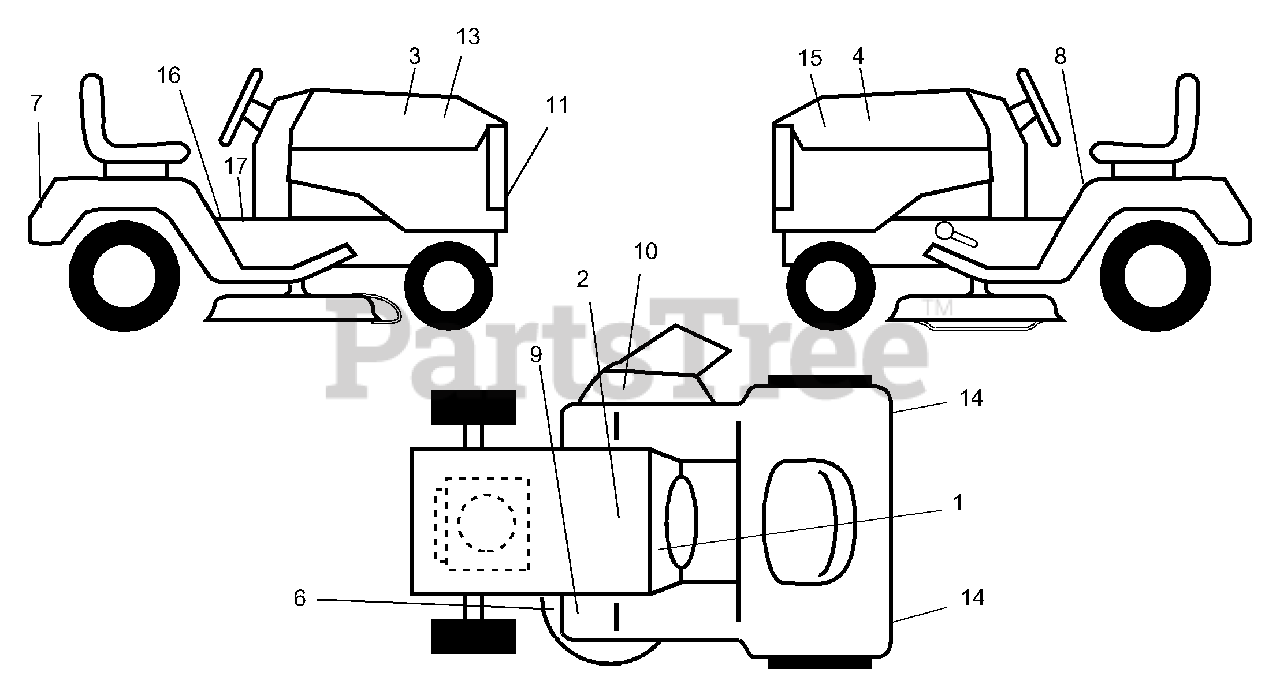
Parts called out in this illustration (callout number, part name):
1	Decal Instruction Dash Eng/fr
2	Decal Bat DAN/POI P/L Symbols
3	Decal Hood RH Husq
4	Decal Hood LH Husq
6	Decal V-Belt Sch
7	Decal Fender Husqvarna
8	Decal Caution Fender Eng/fr
9	Decal Clutch/brake Eng/fr
10	Decal Warning MULT-LANGUAGE
11	Decal Grille Husqvarna
13	Decal Hood RH Husqvarna
14	Reflector Tail Light Red/amber
15	Decal Hood RH Husqvarna
16	Decal Sdl Cold Start Hyd Eng/Fr
17	Decal Brake Parking Saddle
